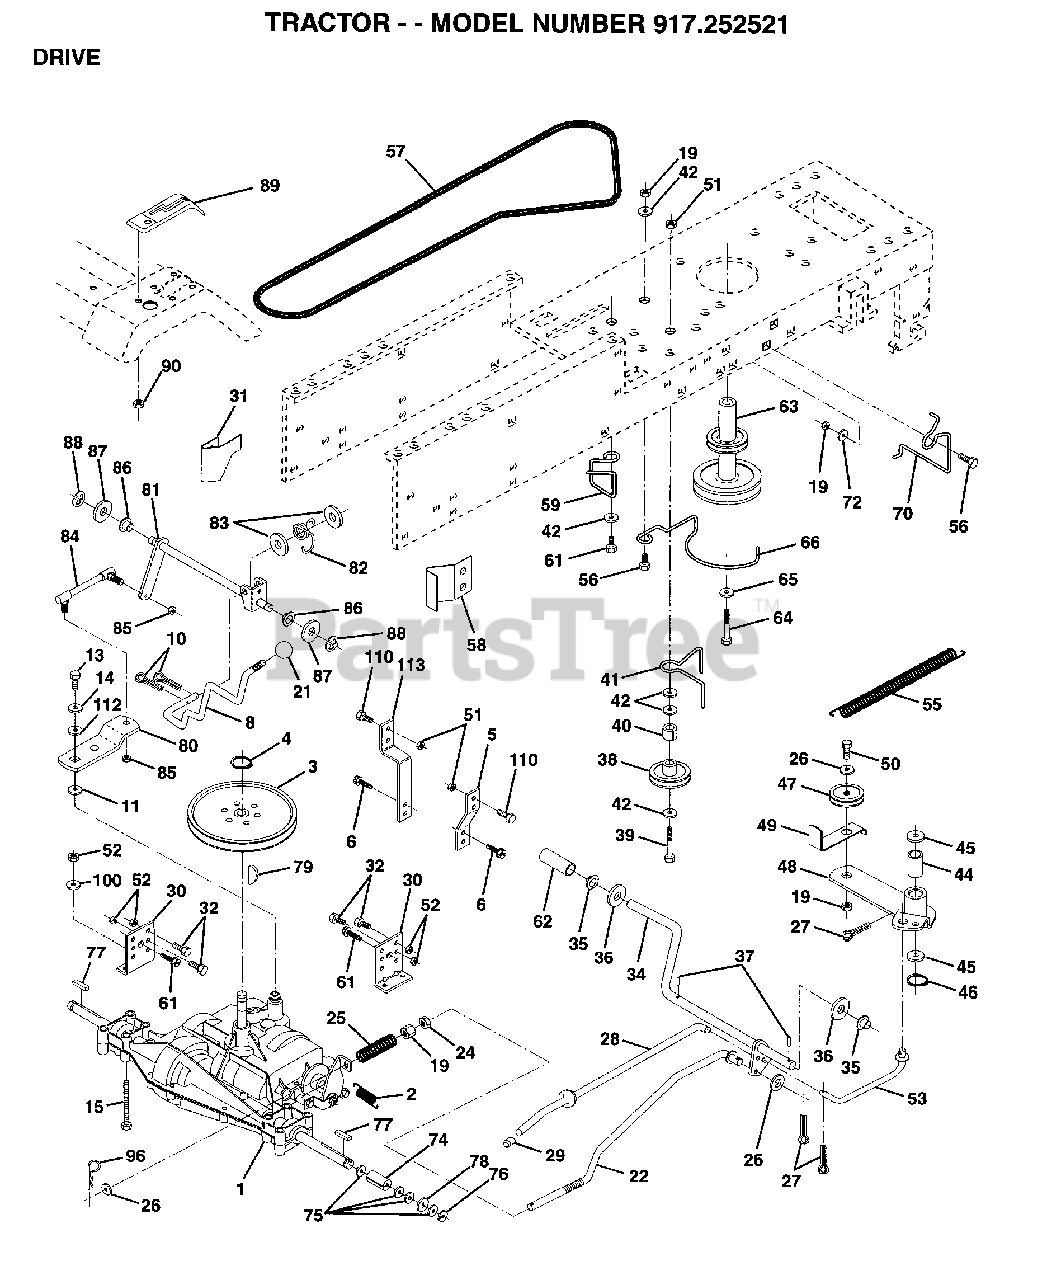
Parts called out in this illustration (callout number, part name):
2	SPRING.BRAKE.RETU
3	PULLEY TRANS
5	STRAP TORQUE
6	SCREW
8	ROD SHIFT FEND LT
10	PIN COTTER 1/8
11	WASH-SHFT PLT LT
12	WASHER LT
13	BOLT.1/4-28.W/PAT
15	BOLT HEX
18	BOLT, 3/8 - 16 X 3/4
21	KNOB T (1/2-HOLE)
22	BRAKE ROD
25	SPRING, BRAKE ROD
28	ROD.BRAKE.PARK.LT
30	TRANSAXLE MTG BKT
31	"KEEPER,BELT LH T"
35	NYLON BEARING
38	PULLEY.IDLER.FLAT
40	SPACER T
41	BELT KEEPER LT
42	WASHER
44	"LY, BEARING"
45	WASHER LT
46	KLIP RING
48	ARM IDLER
49	RETAIN BELT
53	"LINK, CLUTCH T"
55	"SPRING, RETURN LT"
58	"KEEPER,BELT RH T"
59	KEEPER BELT CNTSP
61	SCREW
62	PEDAL COVER T
63	PULLEY.ENGINE
64	BOLT
66	KEEPER.BELT.ENG.L
70	KEEPER BELT ENG
72	WASHER
74	SPACER AXLE
75	WASHER
77	SQUARE KEY
78	WASHER
80	"ARM.SHIFT.20""TIRE"
82	"SPRING,TORSION"
83	WASHER
84	"ROD.TIE.20""P930LT"
85	NUT 1/4-28
86	BUSHING
87	WASHER D
88	KLIP RING
90	NUT
96	RETAINER SPRING 1" ZINC CAD
100	WASHER M
